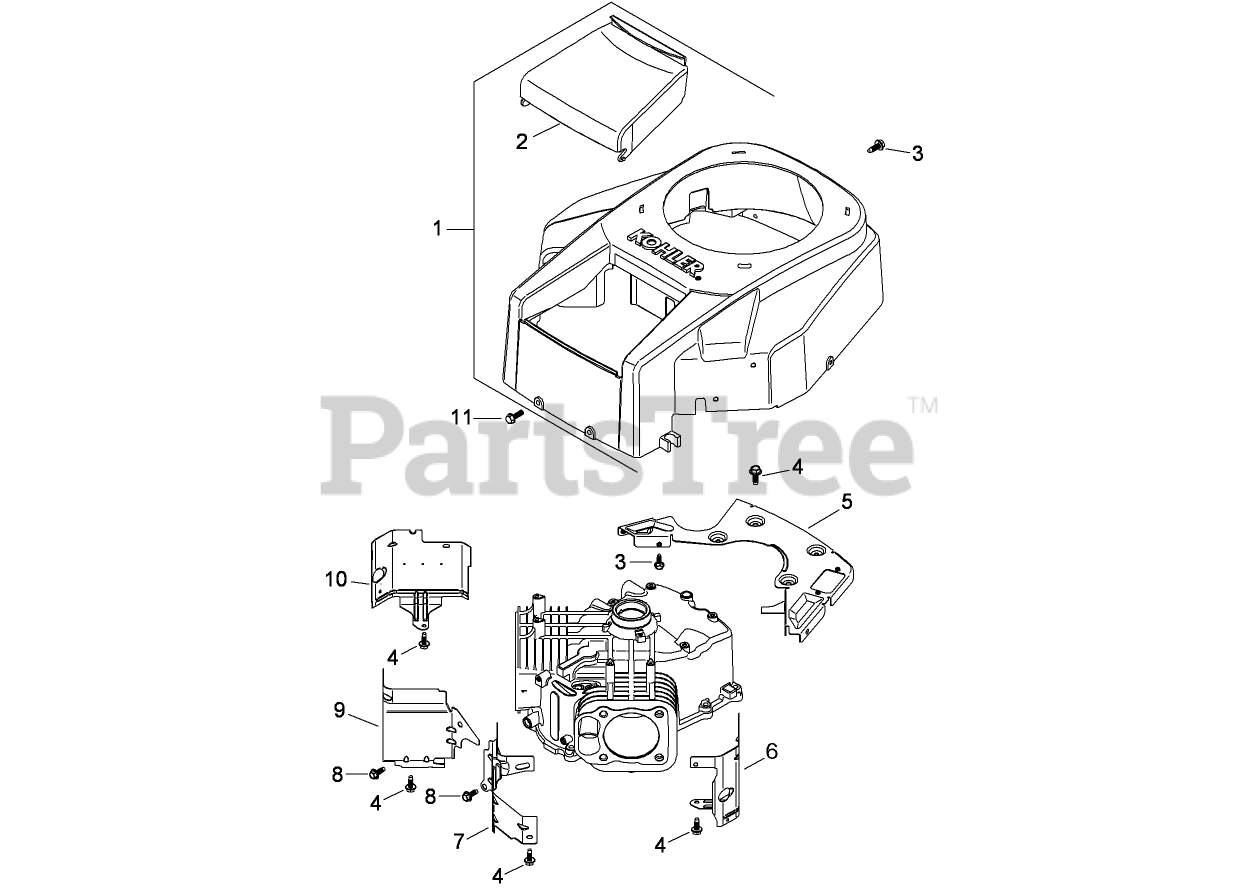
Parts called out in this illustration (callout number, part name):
1	BLOWER HOUSING ASM (W/GUARD) (INCLUDES 2 and 41 037 10-S)
2	COVER-CLEANER, AIR (BLACK)
3	SCREW-FLANGE, THREAD FORMING (M5X0.8X16)
4	SCREW-FLANGE, THREAD FORMING (M6X1.0X16)
5	PLATE-BACKING
6	BAFFLE-BARREL, CYLINDER (No.2 SIDE)
7	BAFFLE-VALLEY (No.2 SIDE)
8	SCREW-HHFTF (M5X.80X10)
9	BAFFLE-VALLEY (No.1 SIDE)
10	BAFFLE-BARREL, CYLINDER (No.1 SIDE)
11	SCREW-TAP (M6X1.7X18)
